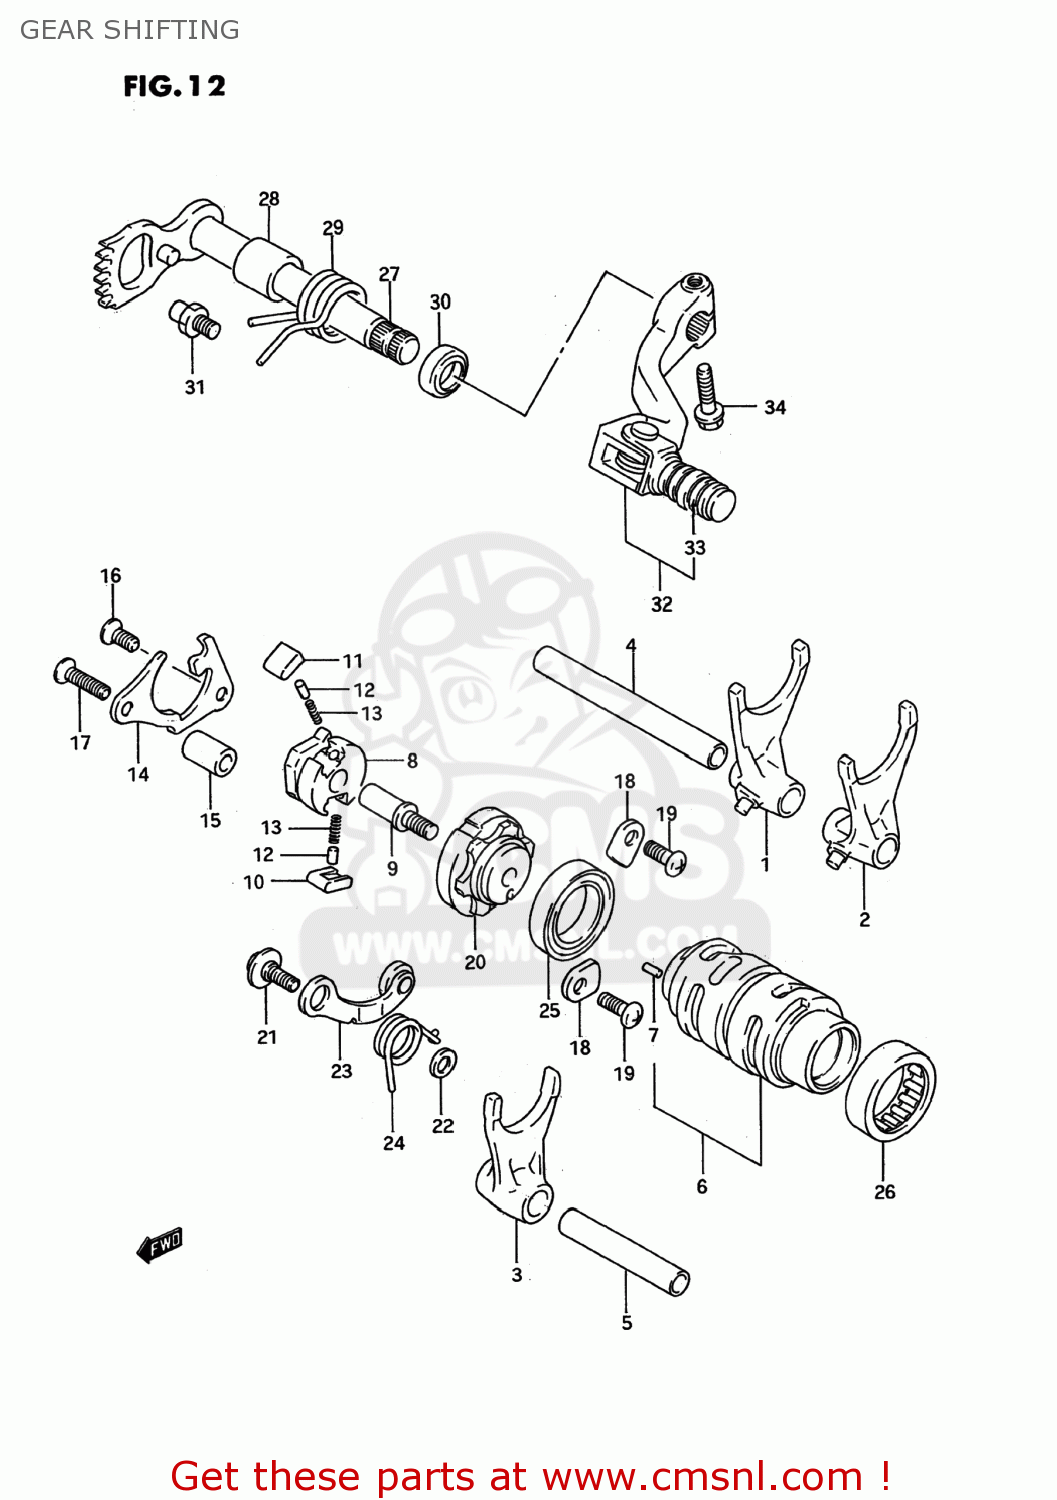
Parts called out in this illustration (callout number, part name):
1	FORK,GEAR SHIFT NO.1
2	FORK,GEAR SHIFT NO.2
3	FORK,GEAR SHIFT NO.3
4	SHAFT,GEAR SHIFT FORK
5	SHAFT,GEAR SHIFT FORK
6	CAM,GEAR SHIFT
7	PIN
8	GEAR,GEARSHIFT CAM DRIVE
9	PIN,SHIFT CAM DRIVEN GEAR
10	PAWL,GEAR SHIFT NO.1
11	PAWL,GEAR SHIFT NO.2
12	PIN(5X8)
13	SPRING
14	LIFTER,GEAR SHIFT POLE
15	SPACER(6.2X12X18)
16	SCREW
17	SCREW
18	RETAINER,COUNTER BEARING,R
19	SCREW
20	PLATE,SHIFT CAM STOPPER
21	BOLT(6X14.3)
22	WASHER
23	STOPPER,SHIFT CAM
24	SPRING
25	BEARING
26	BEARING(30X37X12)
27	SHAFT,GEAR SHIFT
28	SPACER(14X20X17.5)
29	SPRING
30	SEAL,OIL(14X22X6)
31	STOPPER,GEAR SHIFT CAM
32	LEVER ASSEMBLY,GEAR SHIFTING
33	RUBBER,GEAR SHIFT PEDAL
34	BOLT
